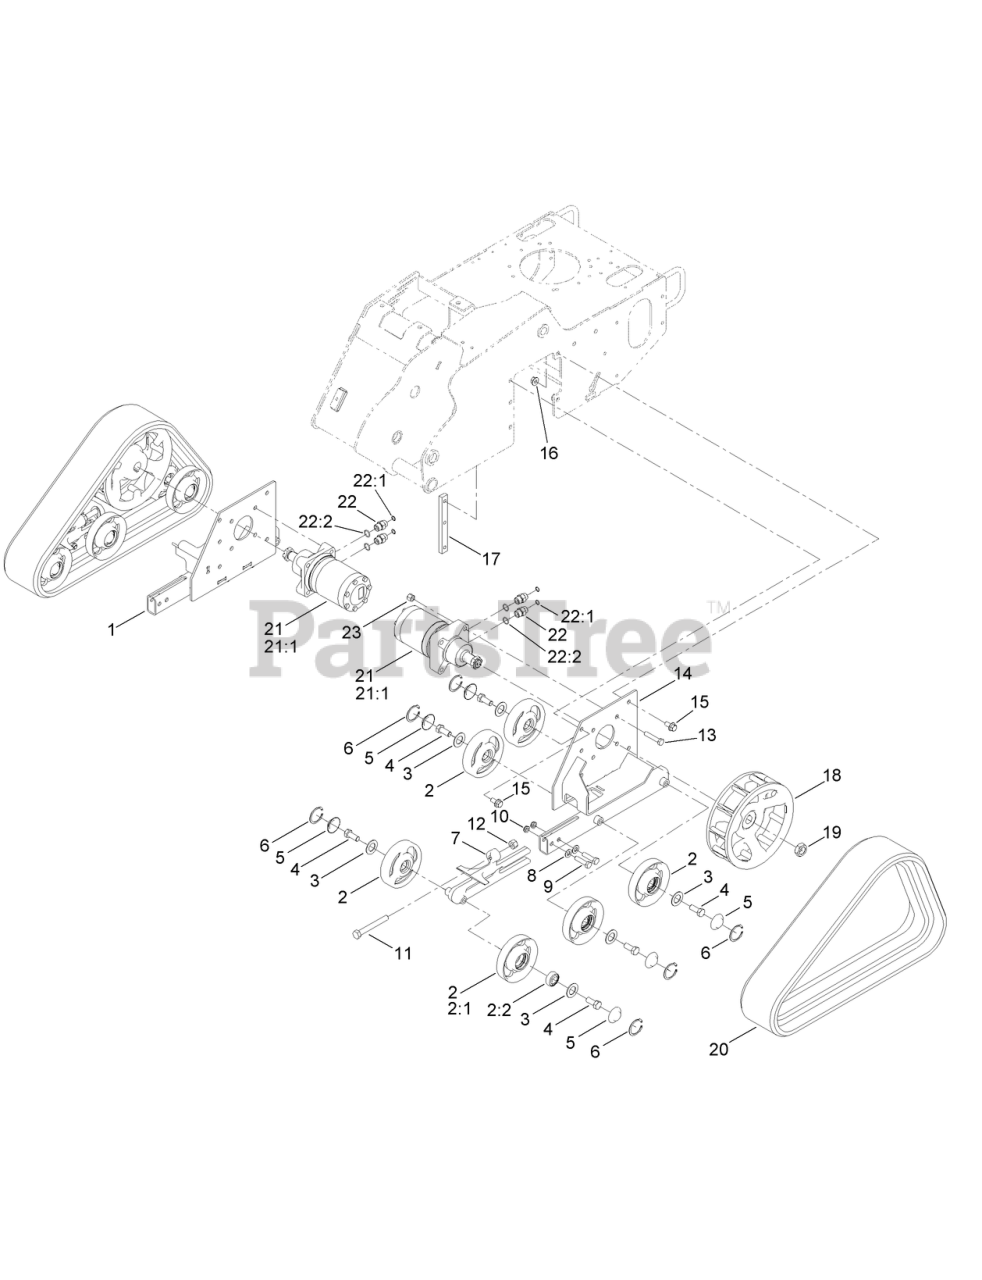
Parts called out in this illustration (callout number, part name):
1	FRAME-TRACK, RH
2	TENSIONER WHEEL ASM
2:1	WHEEL-TRACK
2:2	BEARING-BALL
3	GASKET-BOGIE
4	SCREW-HH
5	CAP-WHEEL, BEARING
6	RING-SNAP, INTERNAL
7	TENSIONER-TRACK
8	WASHER-FLAT
9	SCREW-HH
10	NUT-HEX
11	SCREW-HH, TAP
12	NUT-HEX
13	SCREW-HH
14	FRAME-TRACK, LH
15	SCREW-HHF
16	NUT-HHF
17	BAR-THREAD
18	WHEEL-DRIVE
19	NUT-LOCK
20	TRACK-RUBBER
21	MOTOR-WHEEL, HYDRAULIC
21:1	SEAL KIT
22	FITTING-STRAIGHT
22:1	O-RING
22:2	O-RING
23	NUT-LOCK, NI
